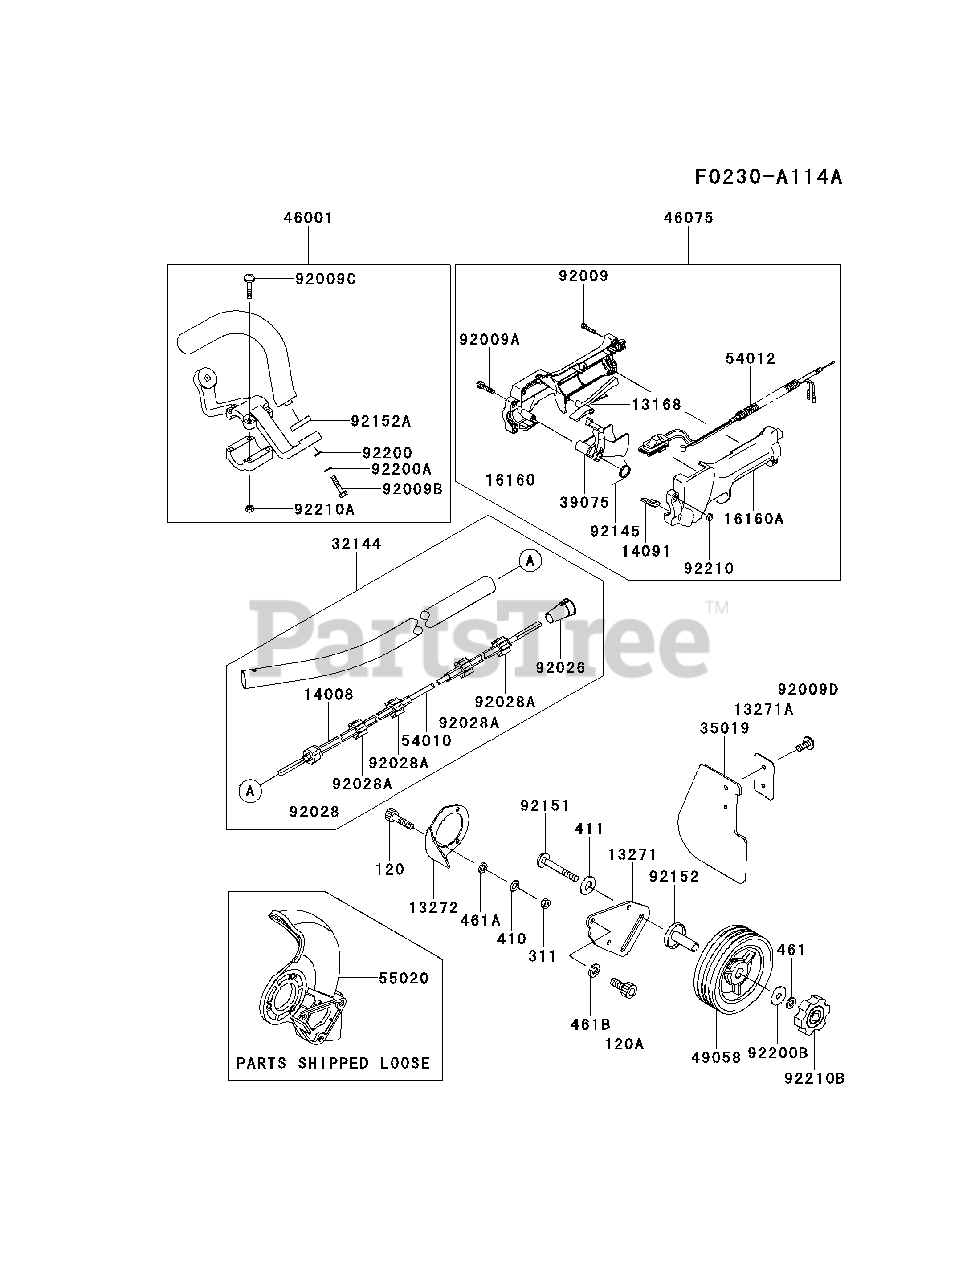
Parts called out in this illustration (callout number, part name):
461	WASHER-SPRING,8MM
461A	WASHER-SPRING,5MM
461B	WASHER-SPRING,6MM
